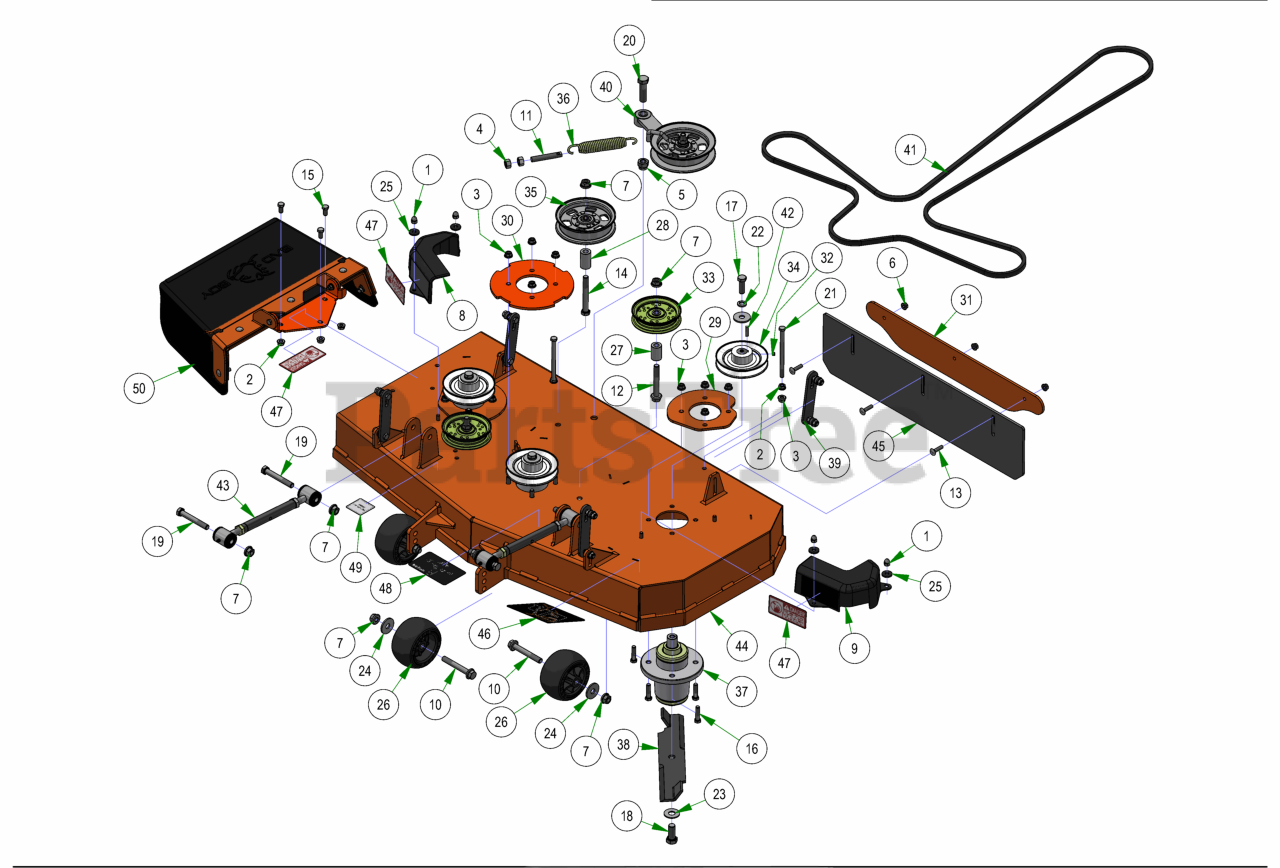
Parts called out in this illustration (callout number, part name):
1	5/16-18 ACORN NUT HIGH-CROWN ZC
2	3/8-16 HEX SERRATED FLANGE NUT HARD/ZINC
3	3/8-16 NYLON INSERT FLANGE LOCKNUT (GR.F) ZINC
4	1/2-13 HEX NUT ZINC
5	5/8-11 NYLON INSERT LOCKNUT ZINC
6	5/16-18 NYLON INSERT FLANGE LOCKNUT ZINC
7	1/2-13 NYLON INSERT FLANGE LOCKNUT ZINC
8	Pulley Cover Chute Side
9	Pulley Cover Non-Chute Side
10	1/2-13 X 90MM HEX FLANGE BOLT W/SHOULDER (GR.8) ZINC
11	All Thread
12	1/2-13 X 3-1/2 HEX FLANGE BOLT (GR.8) ZINC
13	5/16-18 X 1-1/4 CARRIAGE BOLT ZINC
14	1/2-13 X 4 HEX CAP SCREW (GR.8) ZINC YELLOW
15	3/8-16 X 3/4 HEX CAP SCREW (GR.5) ZINC
16	3/8-16 X 1-1/2 HEX CAP SCREW (GR.5) ZINC
17	1/2-20 X 1-1/2 HEX CAP SCREW (GR.5) ZINC
18	5/8-18 X 1-1/2 HEX CAP SCREW (GR.8) ZINC YELLOW
19	1/2-13 X 3-1/2 HEX CAP SCREW (GR.5) ZINC
20	5/8-11 X 2-1/4 HEX CAP SCREW (GR.5) ZINC
21	3/8-16 X 5-1/2 HEX CAP SCREW (GR.5) ZINC
22	1/2 SPLIT LOCKWASHER (GR.8) ZINC/YELLOW
23	5/8 USS FLAT WASHER (1-3/4" OD) GR.8 ZINC YELLOW
24	1/2 BELLEVILLE WASHER (1-5/8 OD X .140 THK) ZINC
25	.360 ID X .983 OD X .120 THICK FLAT WASHER NYLON BLACK
26	Deck Wheel
27	.502 ID X .750 OD X 1.500 Long Spacer
28	1 3/4" Pulley Spacer
29	42&48 Deck Spindle Support Plate
30	Deck Spindle Support Plate
31	2023 4" & 5" Stripping Kit Plate
32	5/16-24 X 1/4 SOCKET SET SCREW (CUP PT) PLAIN
33	4 3/4 Idler Pulley - ABFI-76
34	42 Maverick HD Spindle Pulley
35	5-3/4 Idler Pulley
36	Deck Idler Spring
37	OUTLAW SPINDLE ASSEMBLY
38	42" High Lift Blade-Outlaw
39	Deck Hanger Assembly
40	Maverick HD & Down Deck Idler Assembly
41	2023 42" Deck Belt
42	1/4 X 1 SQ MACHINERY KEY 1018 STL PLN
43	2018 Maverick Turnbuckle (Top Link)
44	2025 42" x 5" Deck
45	2023 ZT Stripping Kit Rubber
46	42" Grip Deck Decal
47	Danger Decal-Spindle/Discharge
48	Deck Belt Route Decal
49	Deck Impact Patent Decal 9591803
50	ZT Chute Assembly
